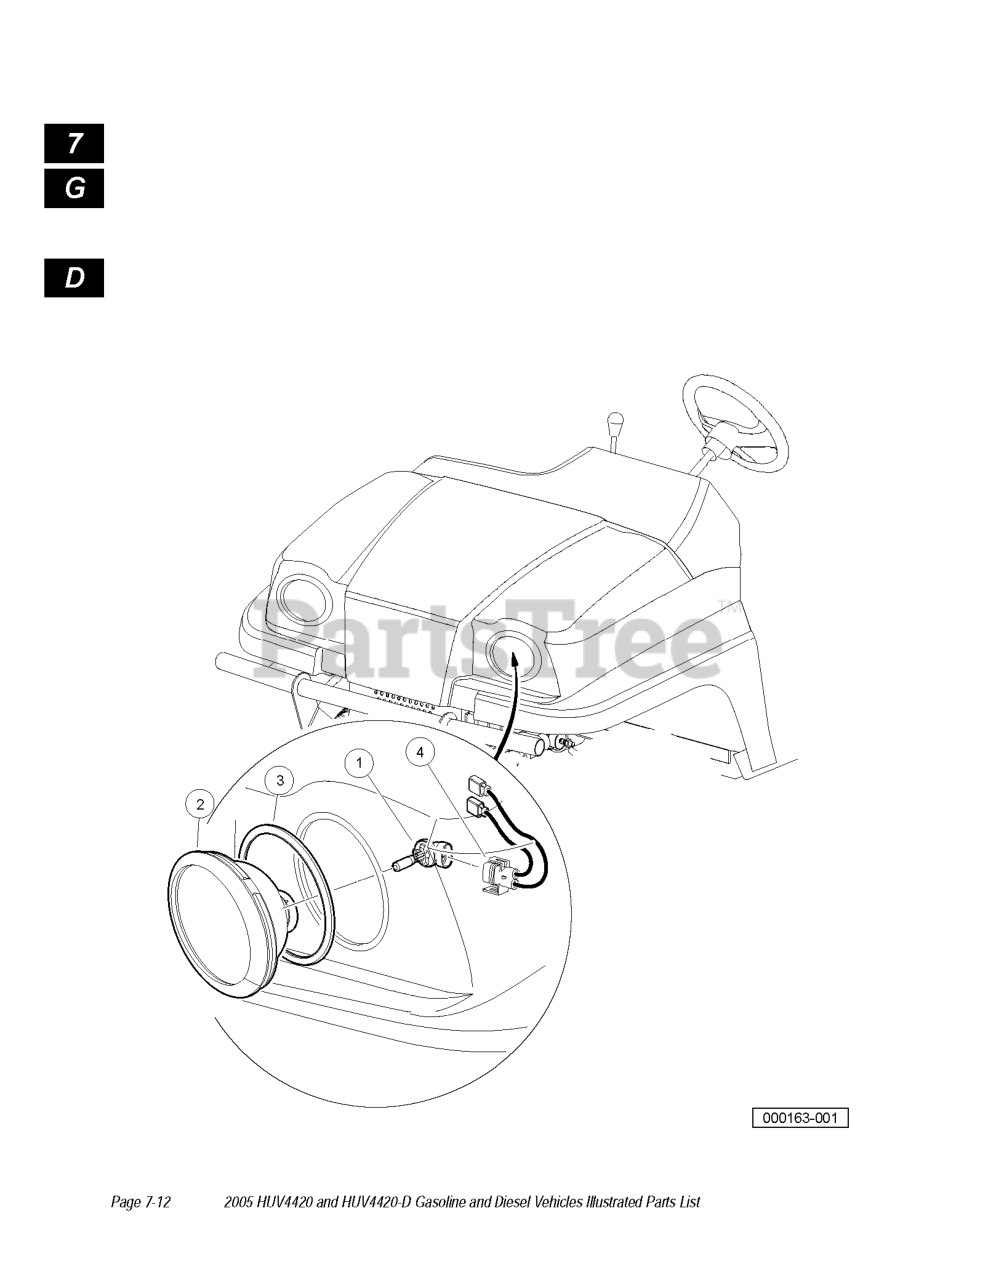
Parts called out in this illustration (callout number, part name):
1	HEADLIGHT ASSY, DRIVER
2	SPACER-HEADLIGHT-OVAL
3	HARNESS-HADLIGHT
4	BULB, HEADLIGHT, OVAL
